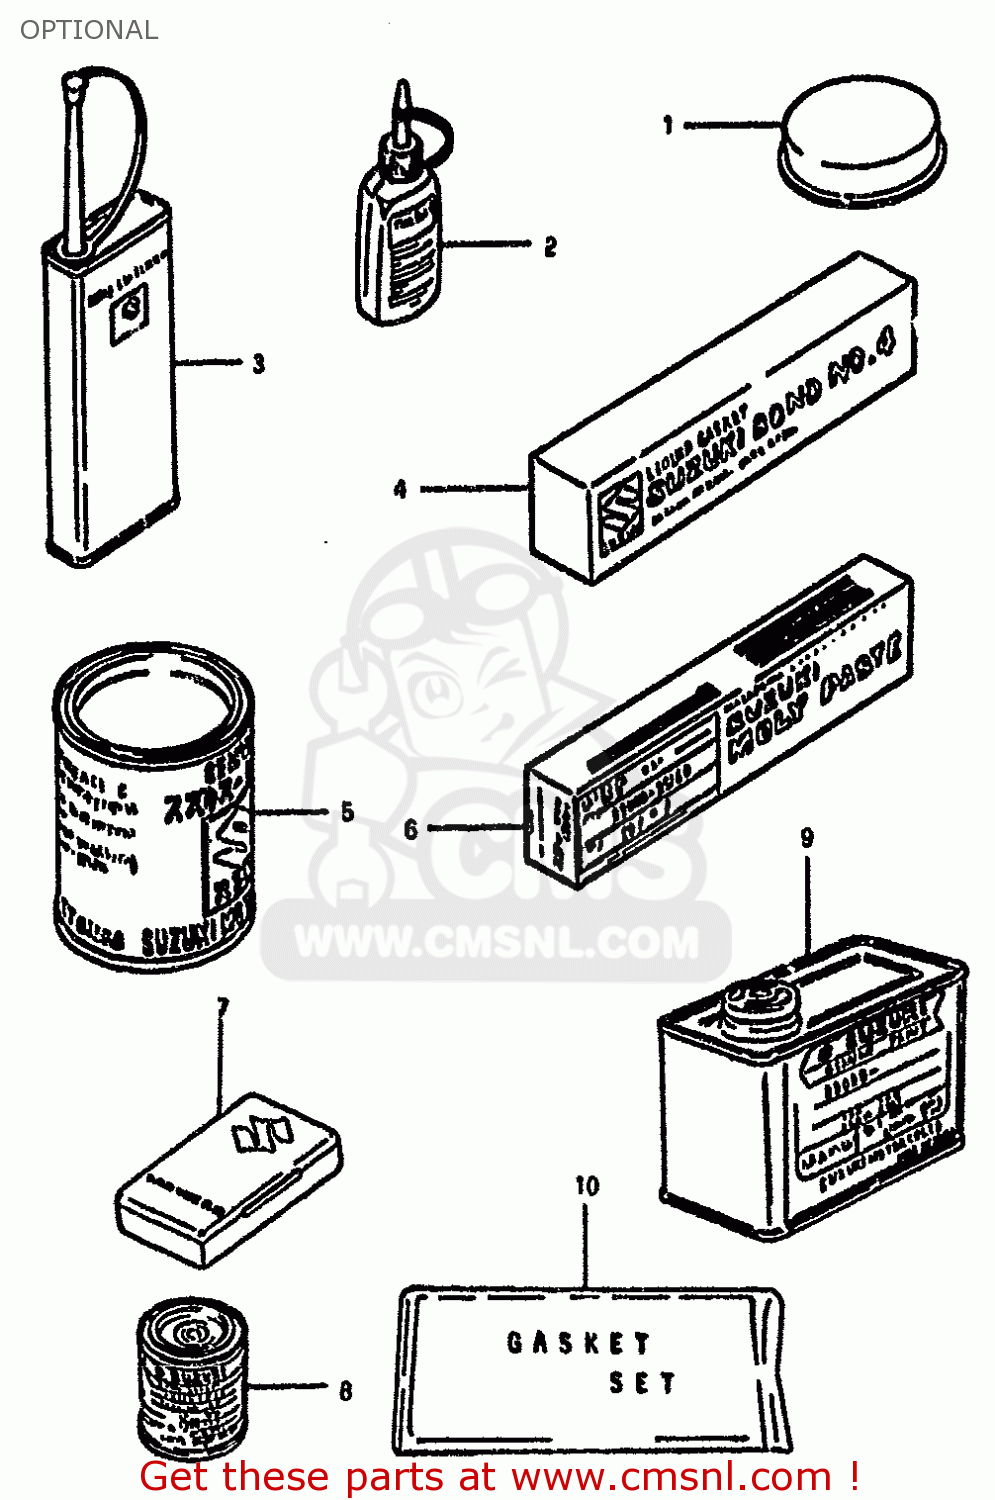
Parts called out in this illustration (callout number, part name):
1	GREASE,PBC FOR BRK PAD 20G
2	THREAD LOCK NO.1342
3	THREAD LOCK NO.1401 CLEAR 200G
4	BOND 1104
5	GREASE(C)EP2 LITHIUM 150G
6	SUZUKI MOLY PASTE
7	TUBE REPARING TOOL
8	PAINT,BLACK
9	PAINT (BLACK)
10	GASKET SET
